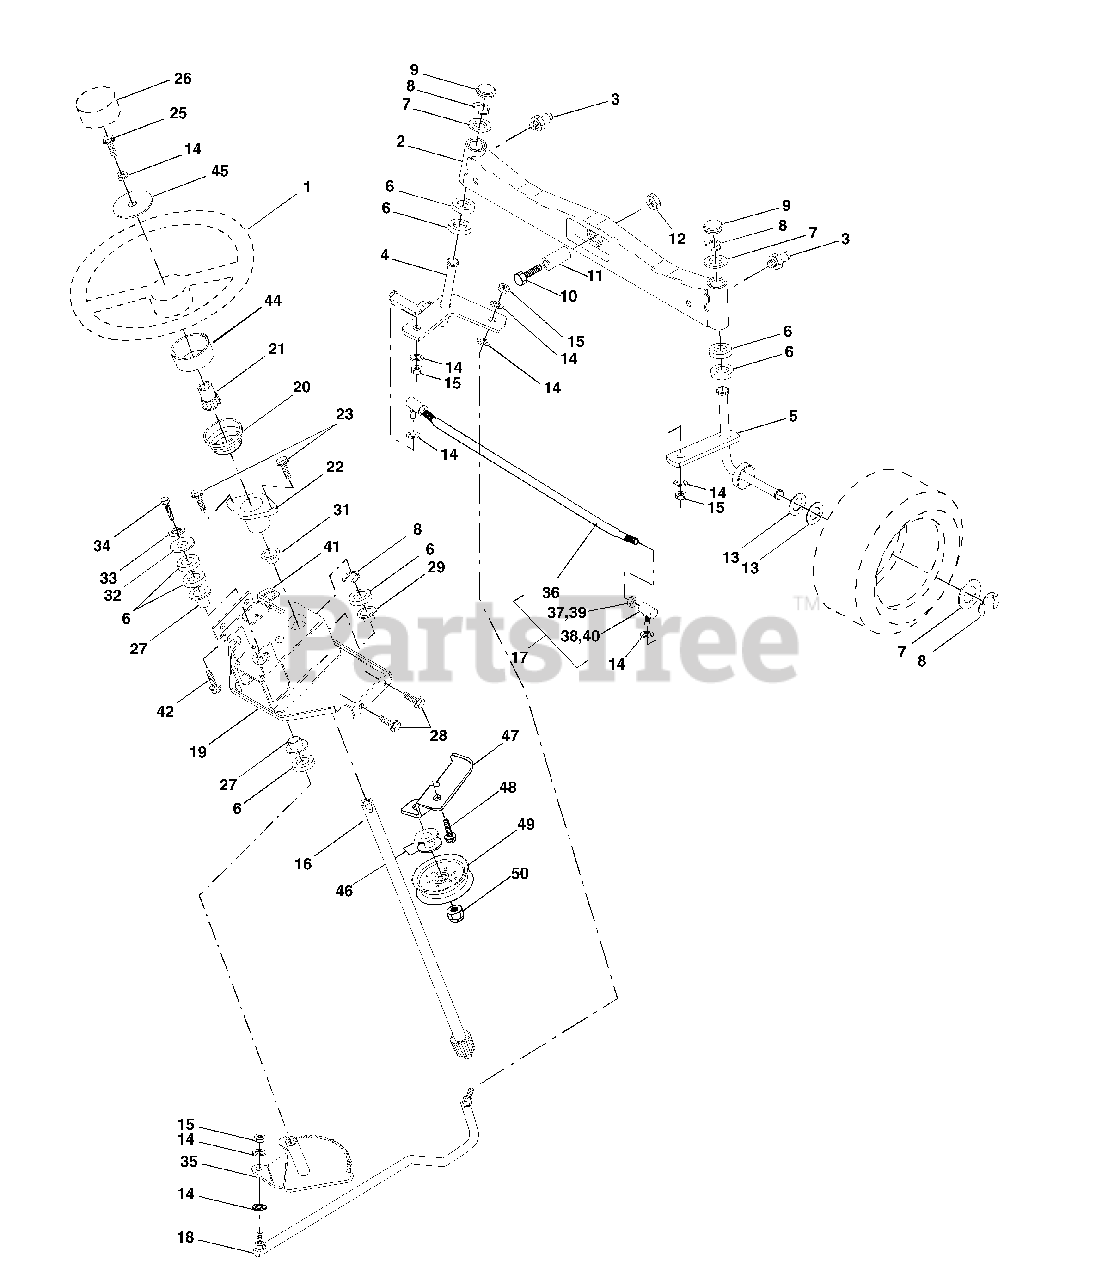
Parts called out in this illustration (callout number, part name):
1	Wheel, Steering
2	Axle Asm., Front
3	Fitting, Grease
4	Spindle Asm, LH
5	Spindle Asm., RH
6	Bearing, Race Thrust Harden
7	Washer 25/32 x 1-5/8 x 16 Ga.
8	Ring, Klip #T5304-75
9	Cap, Spindle
10	Bolt, Fin Hex 5/8-11 x 2-3/4
11	Spacer Brg Axle Front 1.570
12	Nut, Lock Flange 5/8-11 Unc
13	Washer 25/32 x 1-1/4 x 16 Ga.
14	Washer, Lock Hvy Hlcl Spr 3/8
15	Nut Lock Center 3/8-24 Unf
16	Shaft Asm., Steering
17	Rod Asm., Tie Ball J Ball Vgt
18	Draglink, Ball Joint Solid Vgt
19	Support Asm., Steering Vgt
20	Boot Steering
21	Adapter, Wheel Steering
22	Bushing, Strg.
25	Bolt, Fin Hex 3/8-16 x 1 Gr. 5
26	Cap , Wheel Steering
27	Bearing, Col. Strg.
28	Screw 3/8-16 x 3/4
29	Bearing, Flange
31	Bushing, Nyliner Snap
32	Washer 11/32 x 1 x 10 Ga.
33	Washer, Lock Hvy Hlcl Spr 5/16
34	Bolt, Hex Hd 5/16-18 x 3/4
35	Gear, Sector Steering
36	Tie Rod
37	Jam Nut RH Thread
38	Joint Asm. Ball RH Thread
39	Nut Hex Jam 3/8-24 Unf LF
40	Joint Asm Ball LH Service
41	Bracket Switch Inerlock VGT97
42	Screw 5/16-18 x 1/2
44	Extension Steering Premium
45	Washer 13/32 x 1-1/2 x 11 Ga.
46	Washer 13/32 x 7/8 x 10 Ga.
47	Bracket Asm. Idler Staionary
48	Screw 3/8-16 x .75
49	Pulley Idler Flat
50	Nut Lock Flg. 3/8-16 Unc
